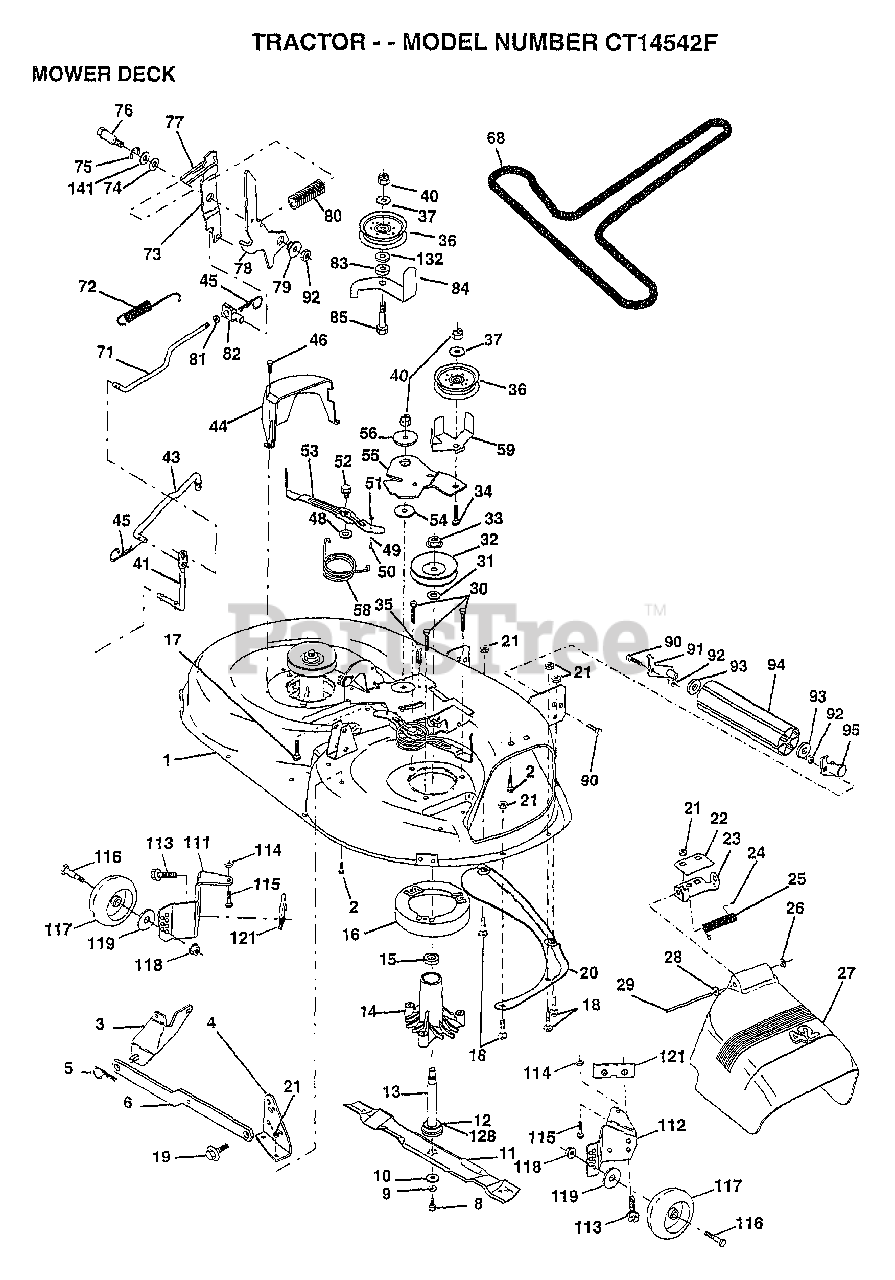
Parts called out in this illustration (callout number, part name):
1	DECK.WELD.42.
2	BOLT
3	BRKT ASM SWAY BAR
4	BRKT DECK SW BAR
8	BLADE BOLT
10	WASHER.HARD.BLADE
11	"BLADE.42"" HIPERF"
12	BEARING.BALL
14	HSG ASM MANDREL
15	BEARING
16	STRIPPER RND MWR
17	BOLT RDHD 3/8-16
18	BOLT
19	BOLT SHD 5/16-18
20	BAFFLE VORTEX 42
22	STIFFENER BRKT
23	DEFLECTOR BRKT
24	CAP-SLEEVE LT
25	SPRING TORSION
26	NUT PUSH M
27	DEFLECTOR.SHIELD
28	WASHER
29	HINGE ROD
30	"SCREW-THD ROLL,WA"
31	WASHER
32	PULLEY.MANDREL.42
34	BOLT
35	XMAS TREE FASTNER
36	FLAT IDLER PULLEY
37	WASHER
41	PIVOT ROD
43	ROD CLUTCH W/NIBS
44	GUARD MAND LH BLK
45	RETAINER M
46	SCREW.1/4-20X5/8
48	HARD SMALL WASHER
49	ROLLER ASM-CAM
50	SHOULDER BOLT
51	LOCKNUT
52	BOLT.SHLD.5/16-18
54	HARDENED WASHER
55	ARM-IDLER
56	SPACER RETAINER
58	SPRING TORSN BRAK
59	GUARD IDLER TUV
68	BELT.V.T-PATH
71	ROD CLUTCH 38/42
72	SPRING.EXT.RETURN
73	CLUTCH ARM SECOND
74	WASHER
75	RING
76	SHOULDER BOLT
77	SPRING KEEPER
78	ARM CLUTCH PRIMARY
79	BUSHING
80	SPRING.CLUTCH.MWR
81	NUT
82	TRUNION ADJ
83	WASHER
84	"KEEPER-BELT,FIXED"
85	BOLT RDHD 3/8-16
90	BOLT
93	WASHER
111	BRACKET.GWHL.LH.
112	BRACKET.GWHL.RH.
113	SCREW
116	BOLT.SHOULDER
117	WHEEL.GUAGE.MED.
118	LOCKNUT
119	WASHER
121	BRACKET.EXTRD.GWL
128	WASHER.FELT.
132	WASHER GT
141	WASHER .T
